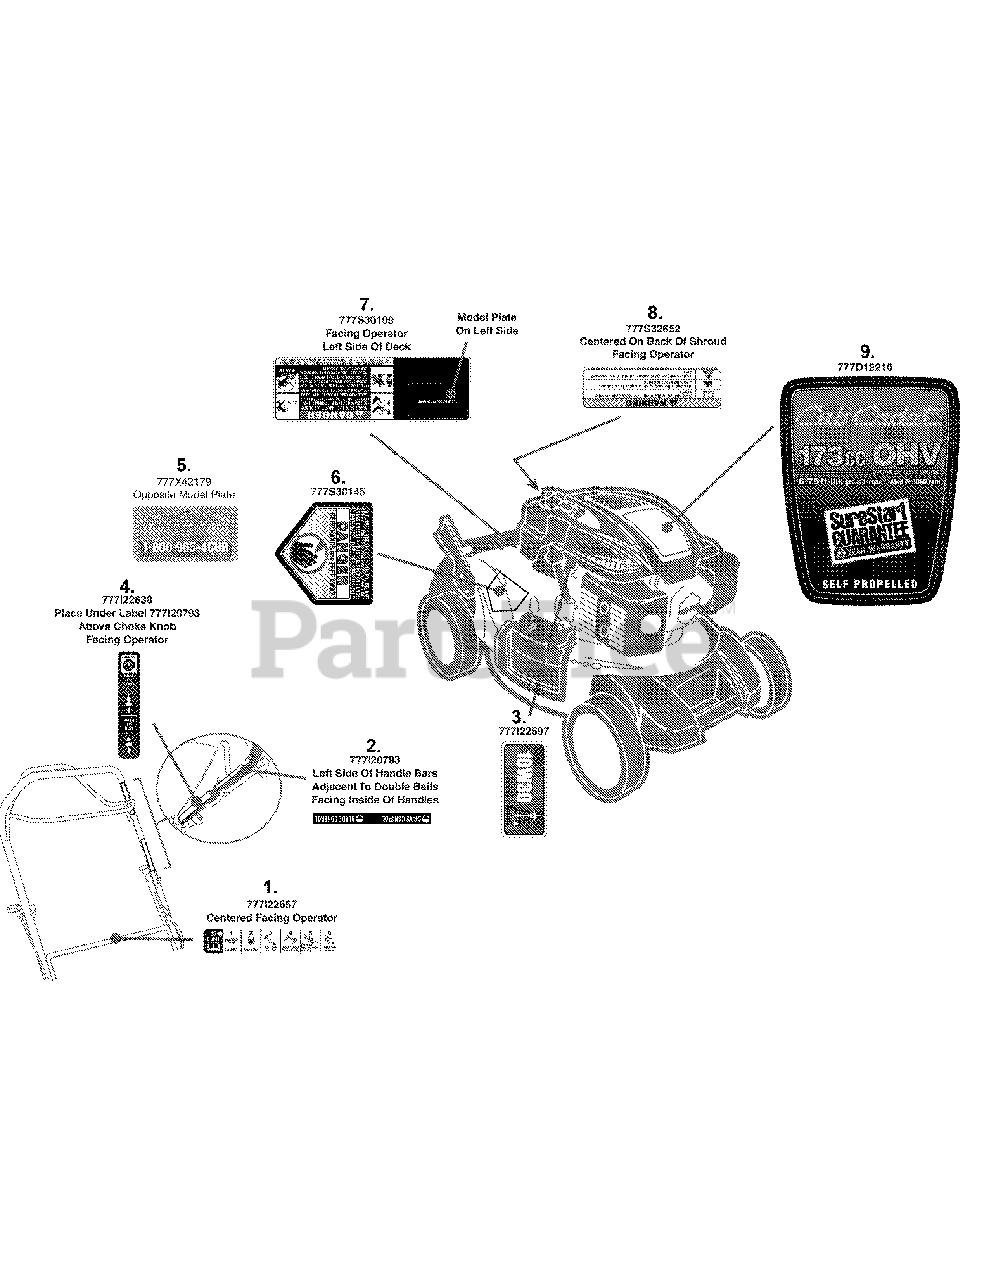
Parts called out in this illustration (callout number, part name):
1	LABEL-MOWER HANDLE
2	LABEL-HANDLE
3	LABEL:MOWER SHROUD
4	LABEL-MOWER HANDLE:CHOKE START/RUN
5	LABEL-CUB HOTLINE
6	LABEL
7	LABEL-MOWER DANGER
8	LABEL:MOWER:ENGINE SHROUD
9	LABEL-173CC SHROUD OHV SELF PROPEL
